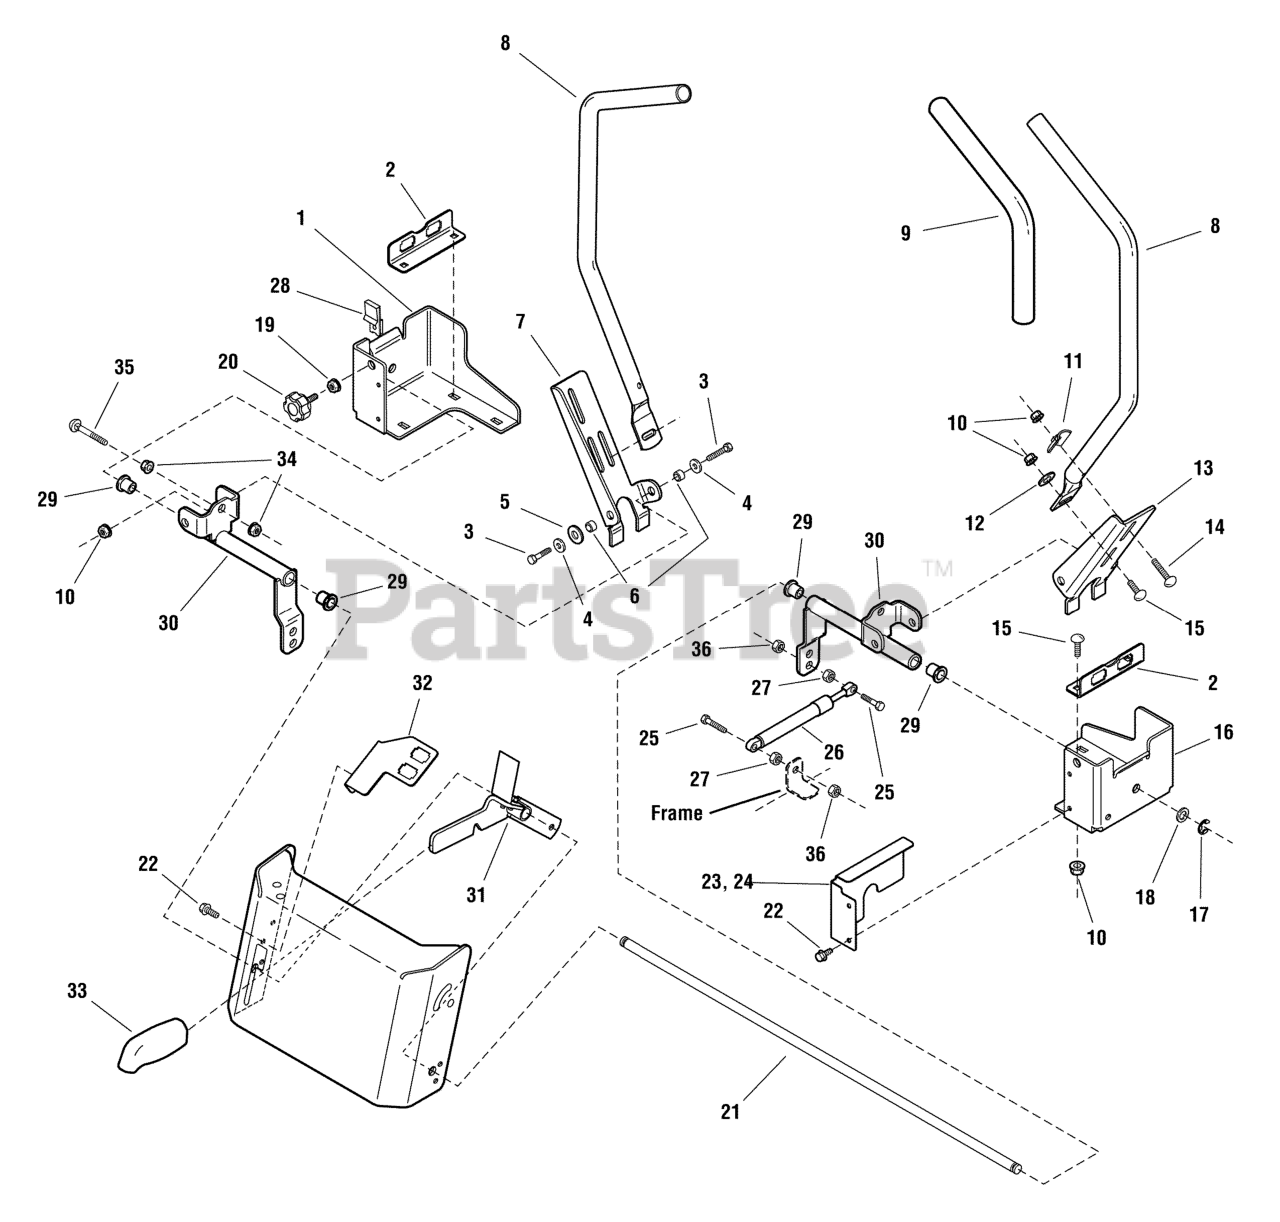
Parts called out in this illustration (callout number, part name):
1	BRACKET, Mounting, R.H.
2	BRACKET, Switch
3	CAPSCREW, Hex Head, 5/16-18 x 1 1/4
4	WASHER, 5/16
5	WASHER, Flat Nylon, 1/2
7	BRACKET, Tube Mount, R.H.
8	TUBE, Control Wand
9	GRIP, Foam Handle Bar
10	NUT, Hex Flange ESNA, 5/16-18
11	CLAMP, Saddle
12	WASHER, 5/16
13	BRACKET, Tube Mount, L.H.
14	CARRIAGE BOLT, 5/16-18 x 1-3/4, G5
15	BOLT, Carriage, Short Neck, 5/16-18 x 1
16	BRACKET, Mounting, L.H.
17	RING, Klipring
18	WASHER, 1/2
19	NUT, Hex Jam 5/16-18
20	KNOB, Extension, Threaded, 5/16-18 x 1-1/4
21	SHAFT, Cross
22	SCREW, Hex Washer Head Taptite, 1/4-20 x 5/8
23	COVER, Lower Handle, L.H.
24	COVER, Lower Handle, R.H.
25	CAPSCREW, Hex Head, 5/16-18 x 1-1/2, G5
26	SHOCK ABSORBER
27	NUT, Hex Jam, 5/16-18
28	NUT, Speed Lug Type, 5/16-18
30	PIVOT ASSEMBLY, Control
31	HANDLE ASSEMBLY, Brake
32	SUPPORT, Switch
34	NUT, Hex Flange Whiz Lock, 5/16-18
35	CARRIABE BOLT, 5/16-18 x 2-1/4, G5
36	NUT, Hex Lock ESNA Light, 5/16-18
